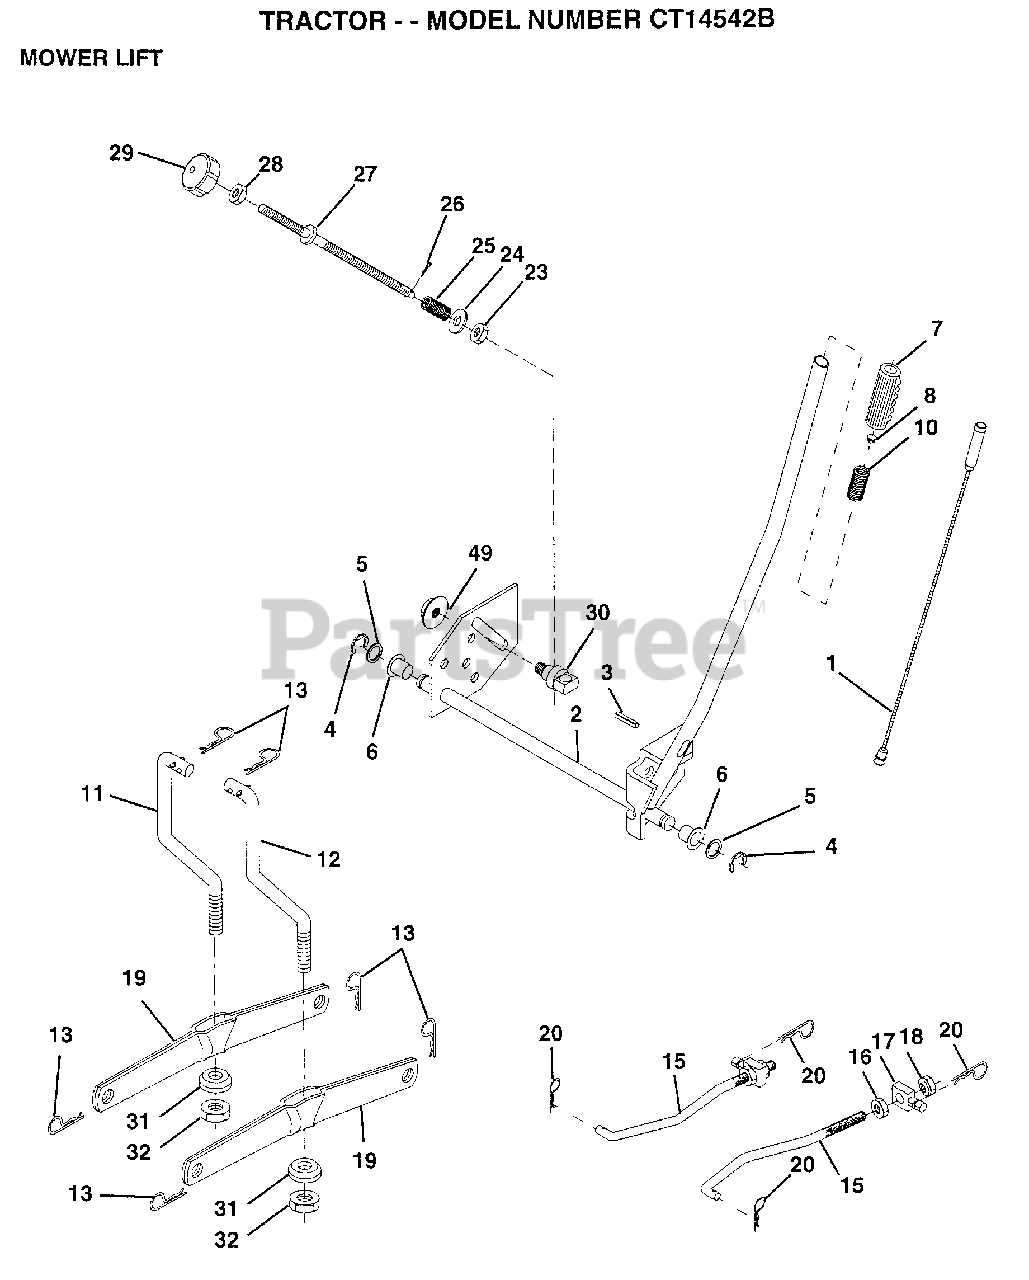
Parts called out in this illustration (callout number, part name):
1	WIRE.ASM.INNER
2	SHAFT.ASM.LIFT.RH
3	PIN GROOVE
5	WASHER
6	NYLON BEARING
7	GRIP
15	LINK.FRONT
16	NUT
17	TRUNION
18	NUT.LK.W/WSH.1/2.
19	ARM SUSP REAR
20	RETAINER.SPRING
23	NUT T
24	WASHER
25	SPRING.COMP.INF.H
27	ROD.ADJ.LIFT
28	NUT
29	KNOB INF 3/8-16
30	TRUNNION
31	BEARING PVT LH
32	NUT.CROWNLOCK.3/8
49	NUT.HXFLG.LOCK.
